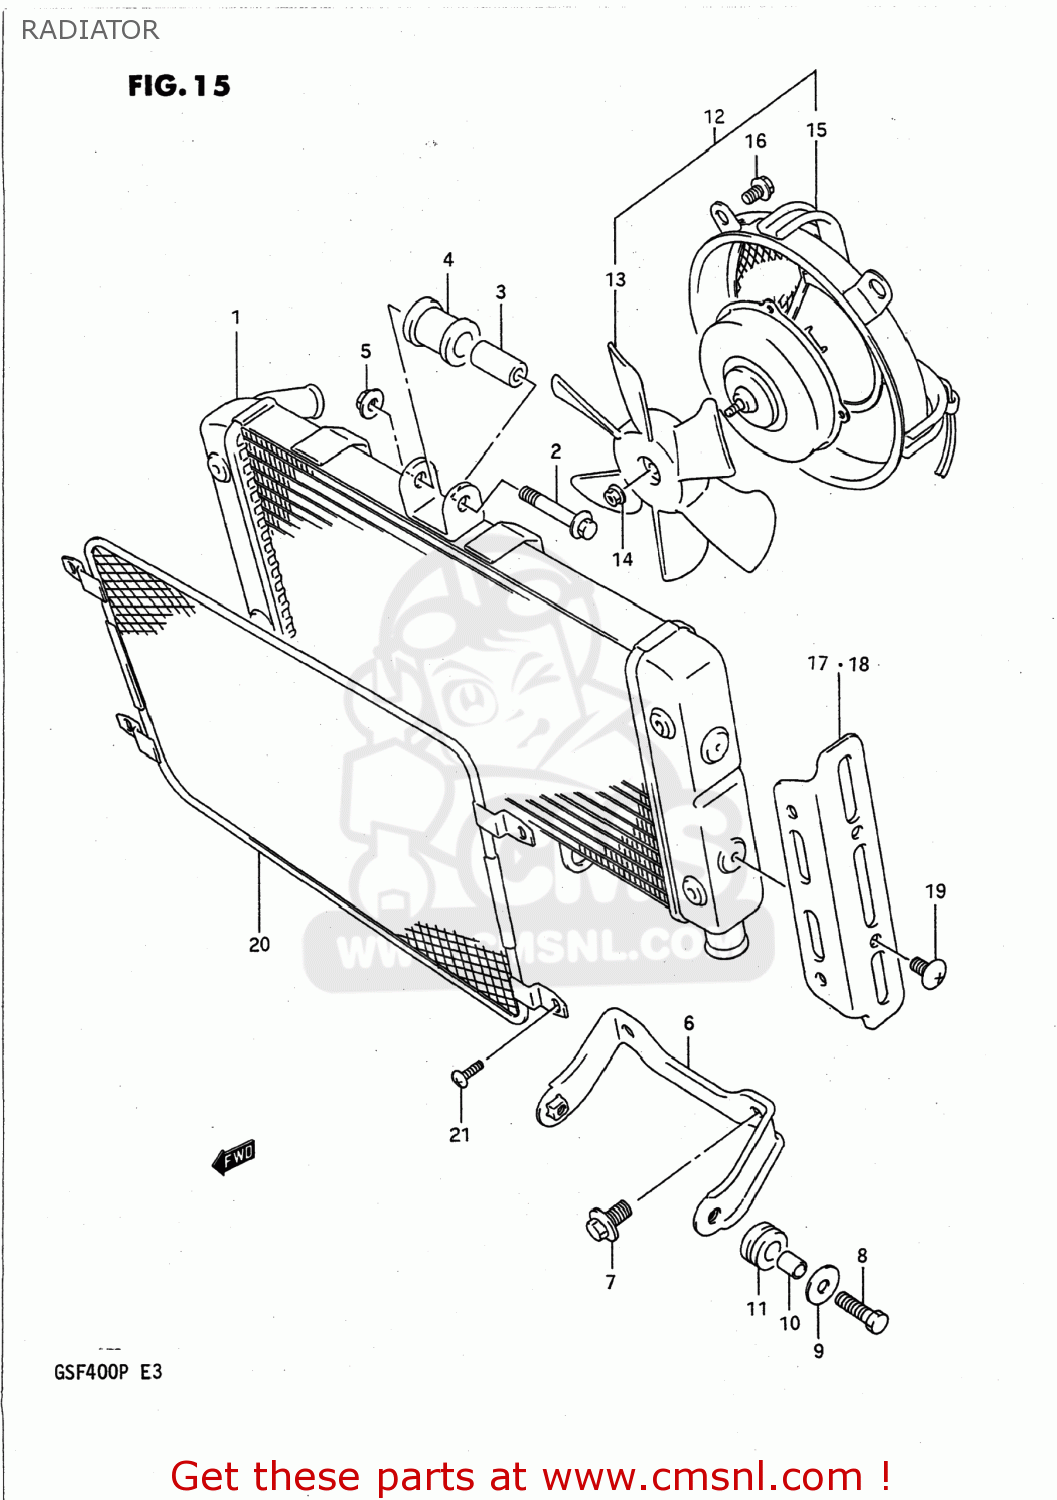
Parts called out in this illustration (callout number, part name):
1	RADIATOR ASSEMBLY,WATER
2	BOLT (6X45)
3	SPACER
4	CUSHION
5	NUT 6MM
6	BRACKET COMP,ROTOR,LOWER
7	BOLT, LOWER
8	BOLT 6X20
9	WASHER (6.5X22X1.6)
10	SPACER (6.8X10X12)
11	CUSHION
12	FAN ASSY,RADIATOR
13	FAN ASSY
14	NUT
15	SHROUD,FAN
16	BOLT
17	COVER,RADIATOR,R
18	COVER,RADIATOR
19	SCREW(6X12)
20	NET,RADIATOR
21	SCREW(4X12)
